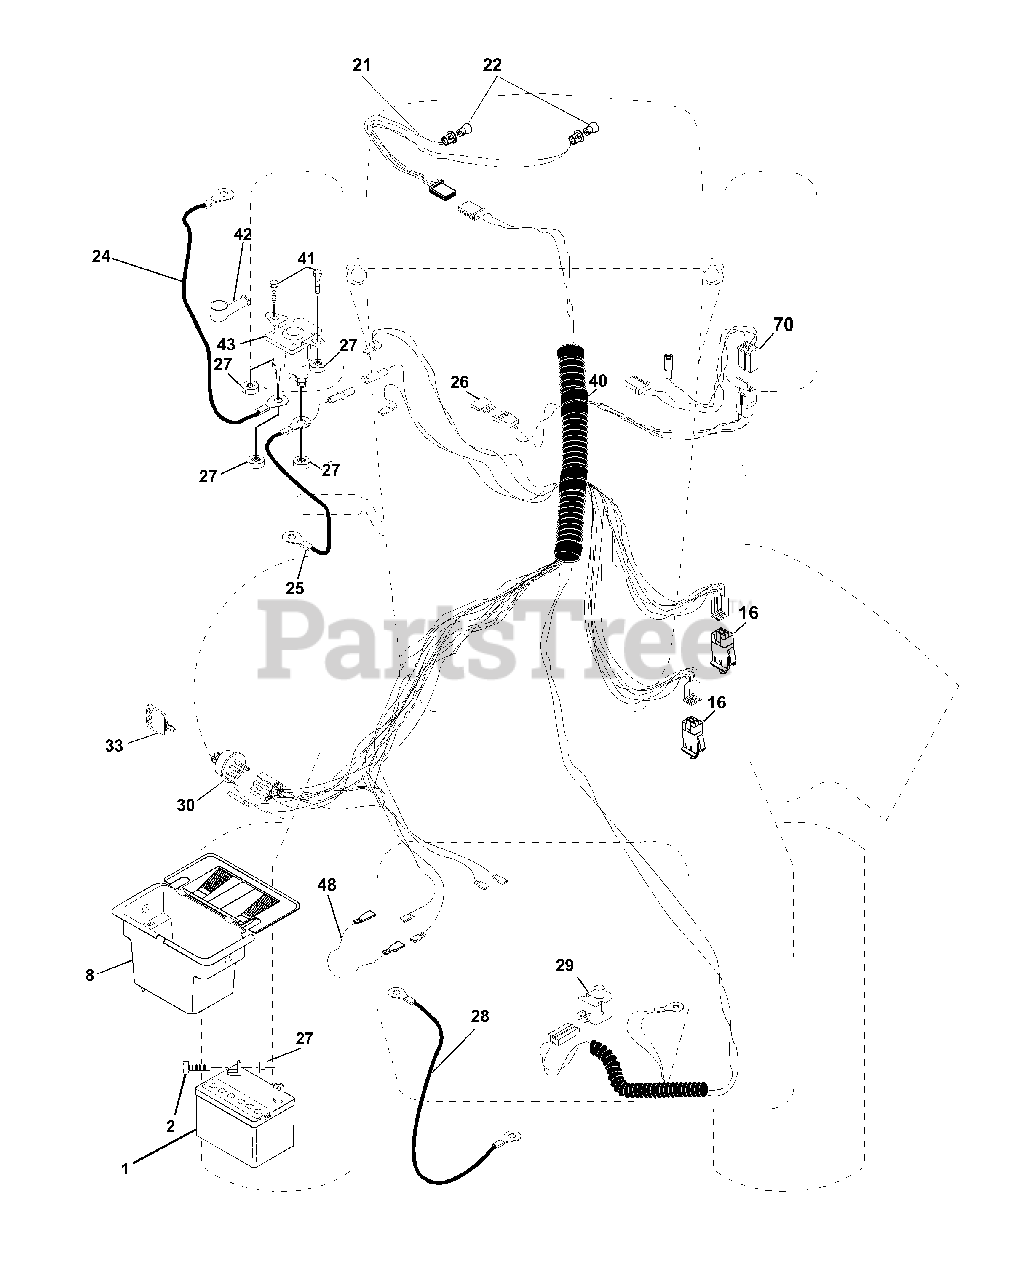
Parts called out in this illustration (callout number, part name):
1	Battery 12 Volt 25 Amp
2	Bolt Hex Hd 1/4-20unc X 3/4
8	Case Battery Mech Hinge
16	Switch Interlock Push-In
21	Harness Asm Light W/4152j
22	Bulb Light #1156
24	Cable Battery 6 Ga 11" red
25	Cable Battery
26	Fuse 15 AMP
27	Nut Keps Hex 1/4-20 Unc
28	Cable Ground 6 Ga 12" black
29	Switch Plunger Nc Gray
30	Switch Ign
33	Key Ign
40	Harness Ign
41	Bolt Blk Fin Hex 1/4-20
42	Cover Terminal Red
43	Solenoid
48	Adapter Ammeter
52	Protection Wire Loop
70	Harness Eng Briggs
